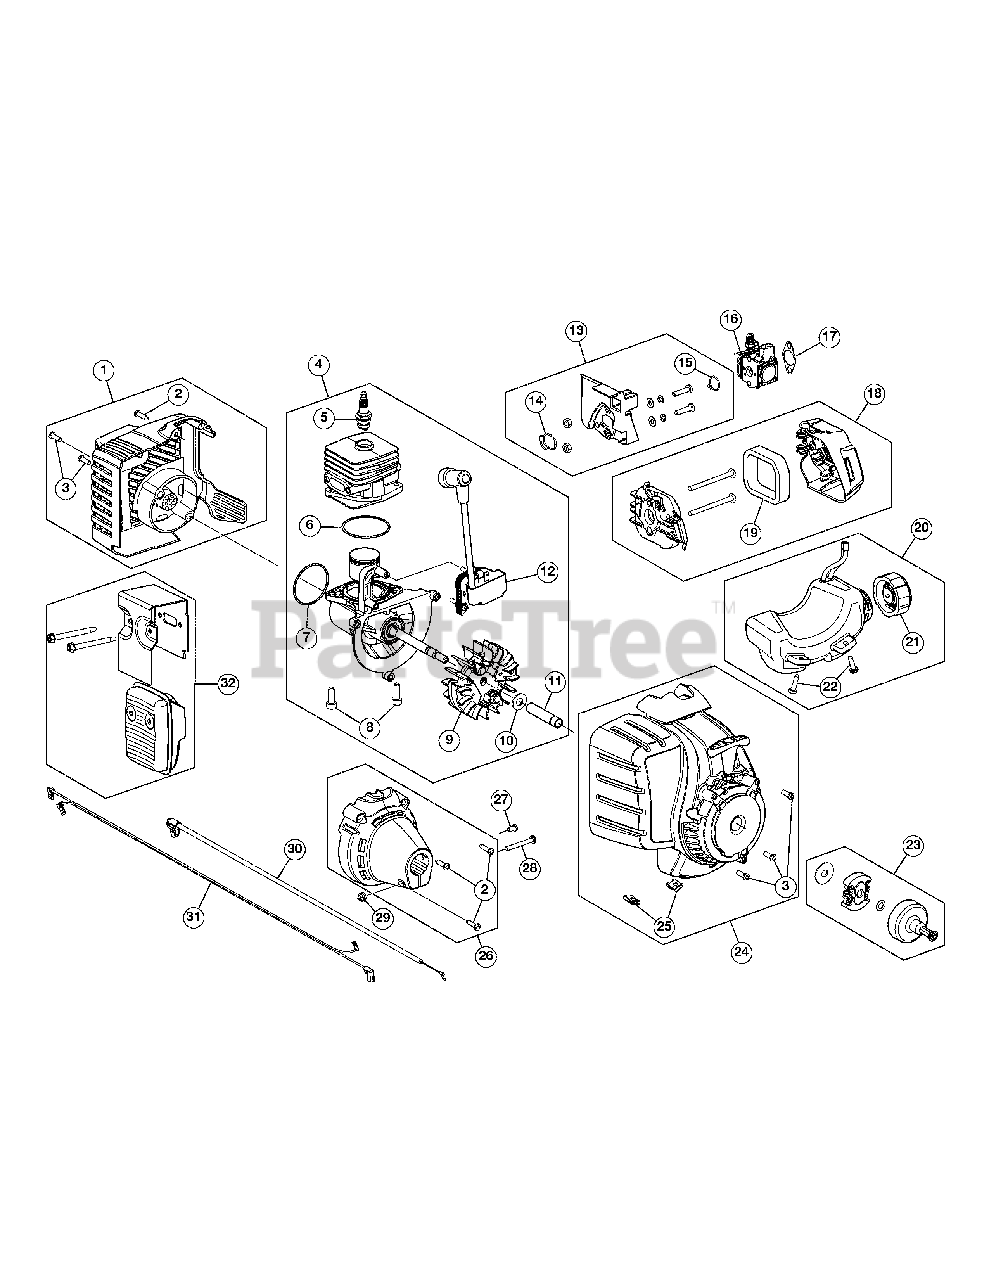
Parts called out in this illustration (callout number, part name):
1	Rear Cover Assembly (Incl. 2 & 3)
2	Cover Screw
3	Rear Housing Screw
4	Short Block Assembly (Incl. 5 - 12)
5	Spark Plug
6	Crankcase O-Ring
7	O-Ring
8	Crankcase Bolt
9	Flywheel Assembly
10	Washer
11	Spacer
12	Module Assembly
13	Insulator Assembly (Incl. 14 & 15)
14	Insulator O-Ring
15	Carburetor O-Ring
16	Carburetor
17	Air Cleaner Gasket
18	Aircleaner Cover Assembly (Incl. 19)
19	Aircleaner Filter
20	Fuel Tank Assembly (Incl. 21 & 22)
21	Fuel Tank Cap
22	Fuel Tank Screw
23	Clutch Assembly
24	Starter Housing (Incl. 3 & 25)
25	U-shaped Nut
26	Clutch Cover (Incl. 2)
27	Anti-rotation Screw
28	Clamp Screw
29	Clamp Nut
30	Throttle Cable
31	Lead Wires
32	Muffler Assembly
